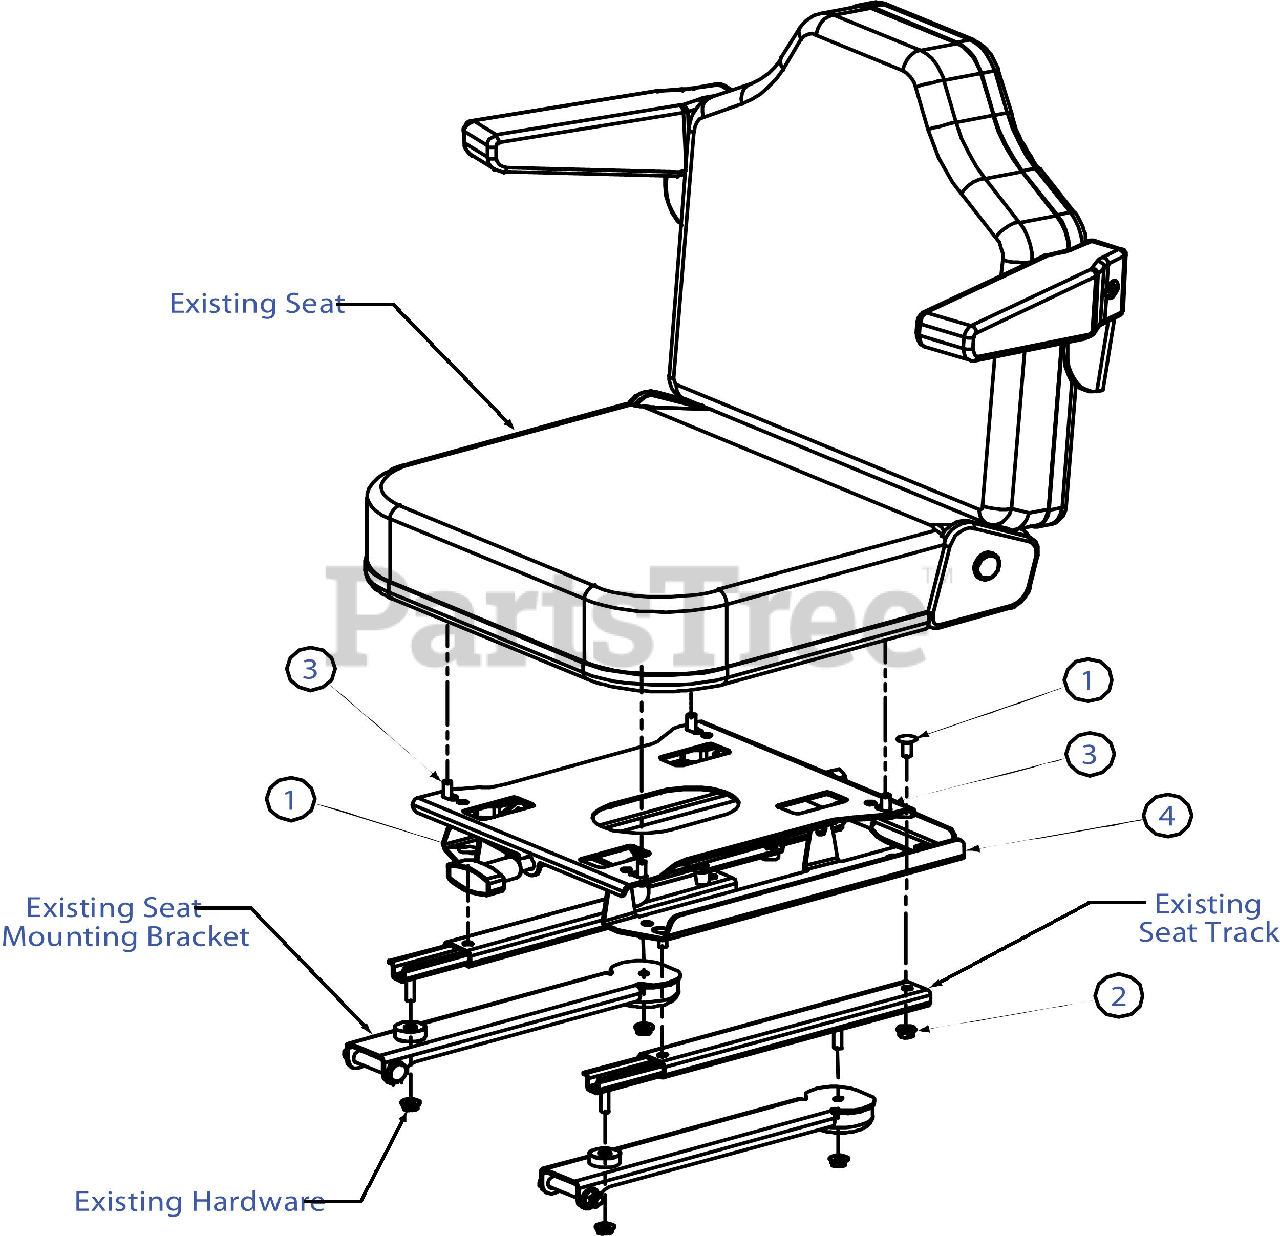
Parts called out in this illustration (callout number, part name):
1	Carriage Bolt, 5/16-18 x .75
2	HEX FLANGE NUT
3	HHCS, 5/16-18 x .75
4	Seat Suspension
